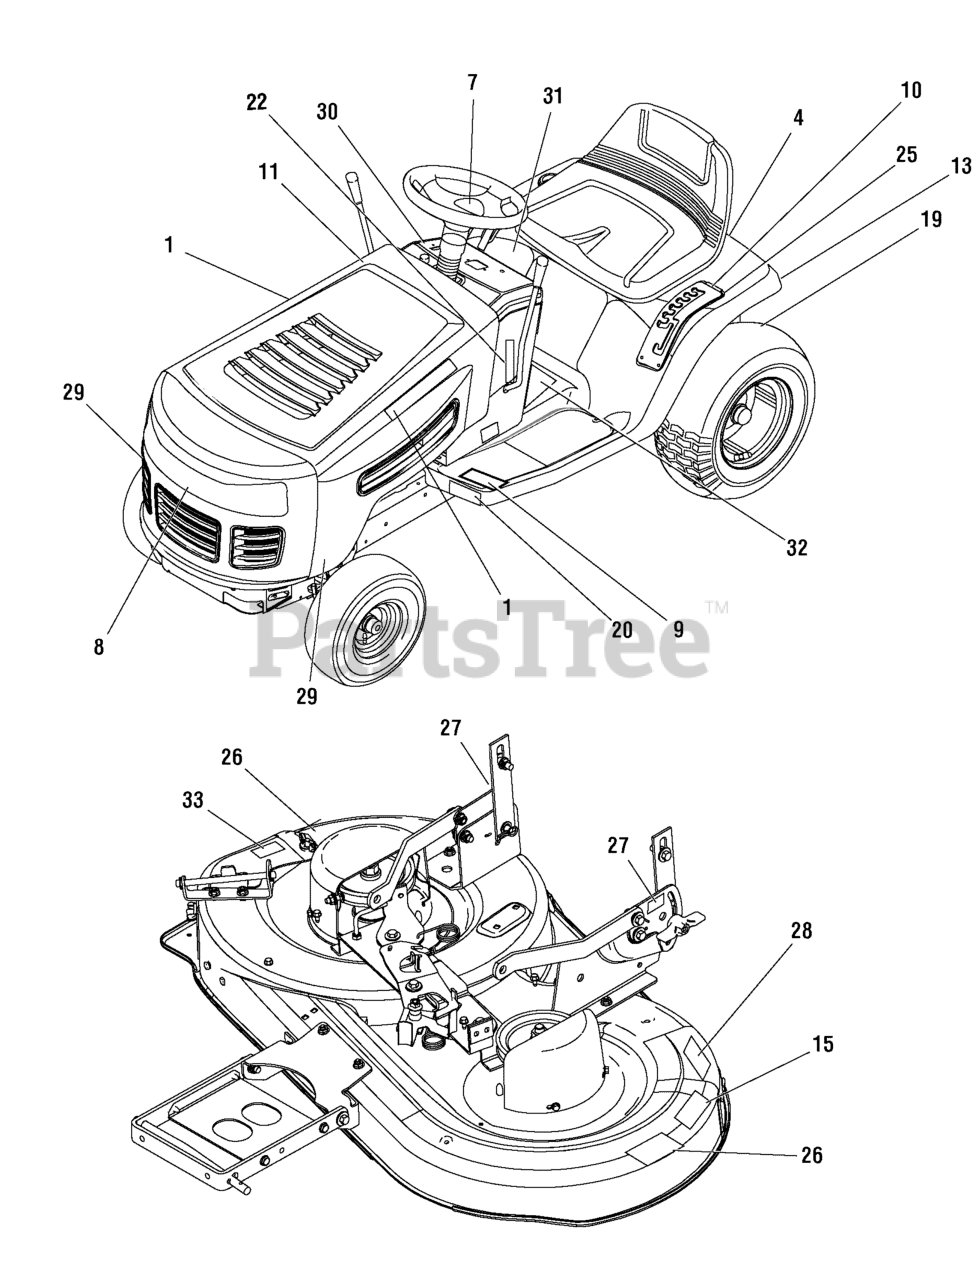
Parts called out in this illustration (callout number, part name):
1	DECAL, Logo, Side Hood
4	DECAL, Murray, Rear
7	DECAL, Steering Wheel
8	DECAL, Front Hood
9	DECAL, Belt/ Clutch
10	DECAL, Deck Level
11	DECAL, Cut Height, 7 Position
13	DECAL, Roll Release
15	DECAL, No Step
19	DECAL, Weight Limitation
20	DECAL, Drive Pedal
22	DECAL, Gas Gauge
25	DECAL, Deck Level
26	DECAL, Danger Do Not Operate w/o Deflector
27	DECAL, Gage, Wheel Instruction
28	DECAL, GAGE WHEEL LEVELING
29	DECAL, MT100
30	DECAL, Dash/ Symbols
31	DECAL, 17.5HP, I/C
32	DECAL, Umber
33	DECAL, Deck Width, 107 cm, 42 in
